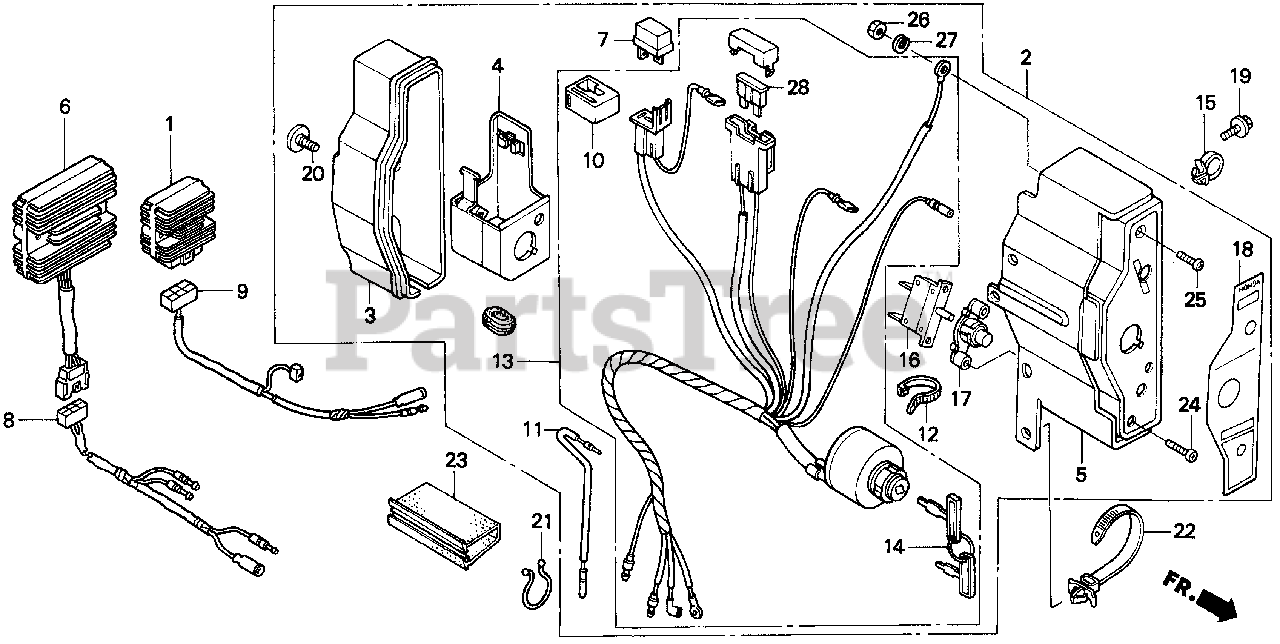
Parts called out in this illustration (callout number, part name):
2	BOX ASSY., CONTROL (EXP-ALERT,3A) *R8* (BRIGHT RED)
3	CASE, CONTROL
4	BRACKET, CASE MOUNTING
5	PANEL, CONTROL *R8**R8* (BRIGHT RED)
7	RECTIFIER ASSY., SILICON (STANLEY)
10	SUSPENSION, CONNECTOR
11	SUB-HARNESS
12	BAND
13	SWITCH ASSY., COMBINATION
14	KEY
15	HOLDER, STOP SWITCH WIRE
16	PROTECTOR, CIRCUIT (3.5A)
17	LENS ASSY., PROTECTOR
18	PANEL, CONTROL BOX (EXTERNAL)
19	BOLT, FLANGE (6X12) (CT200)
20	SCREW, SPECIAL (6X12)
21	CLIP, PURSE LOCK
22	STRAP, CABLE (118MM) *NH1L* (BLACK)
23	TUBE, FASTENER (30)
24	SCREW, PAN (3X12)
25	SCREW, PAN (4X12)
26	NUT, HEX. (4MM)
27	WASHER, SPRING (4MM)
28	FUSE, BLADE (15A)
